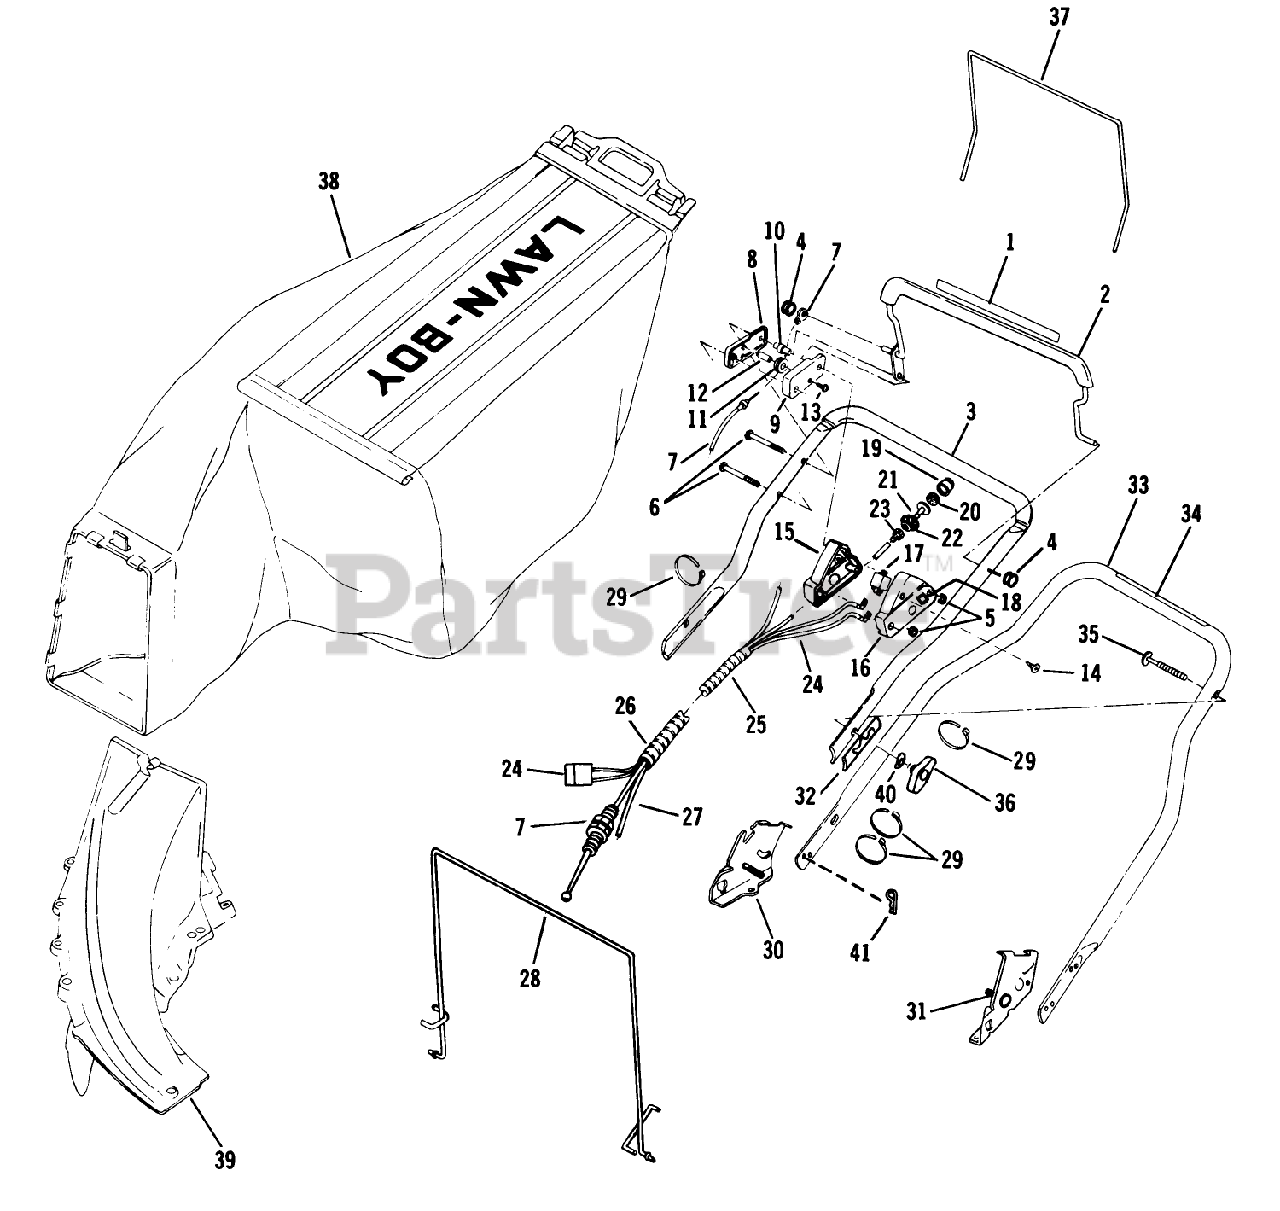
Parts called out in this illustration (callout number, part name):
5	NUT C/LOCK E
12	PIN SKF
14	SCREW LAWRENCE
20	FILTER S
23	LOCKNUT S
28	HANGER AY
32	BRACKET R/B 613462
35	Screw-Folding Handle
36	NUT-WING
40	WASHER-CURVED
41	HAIR PIN
